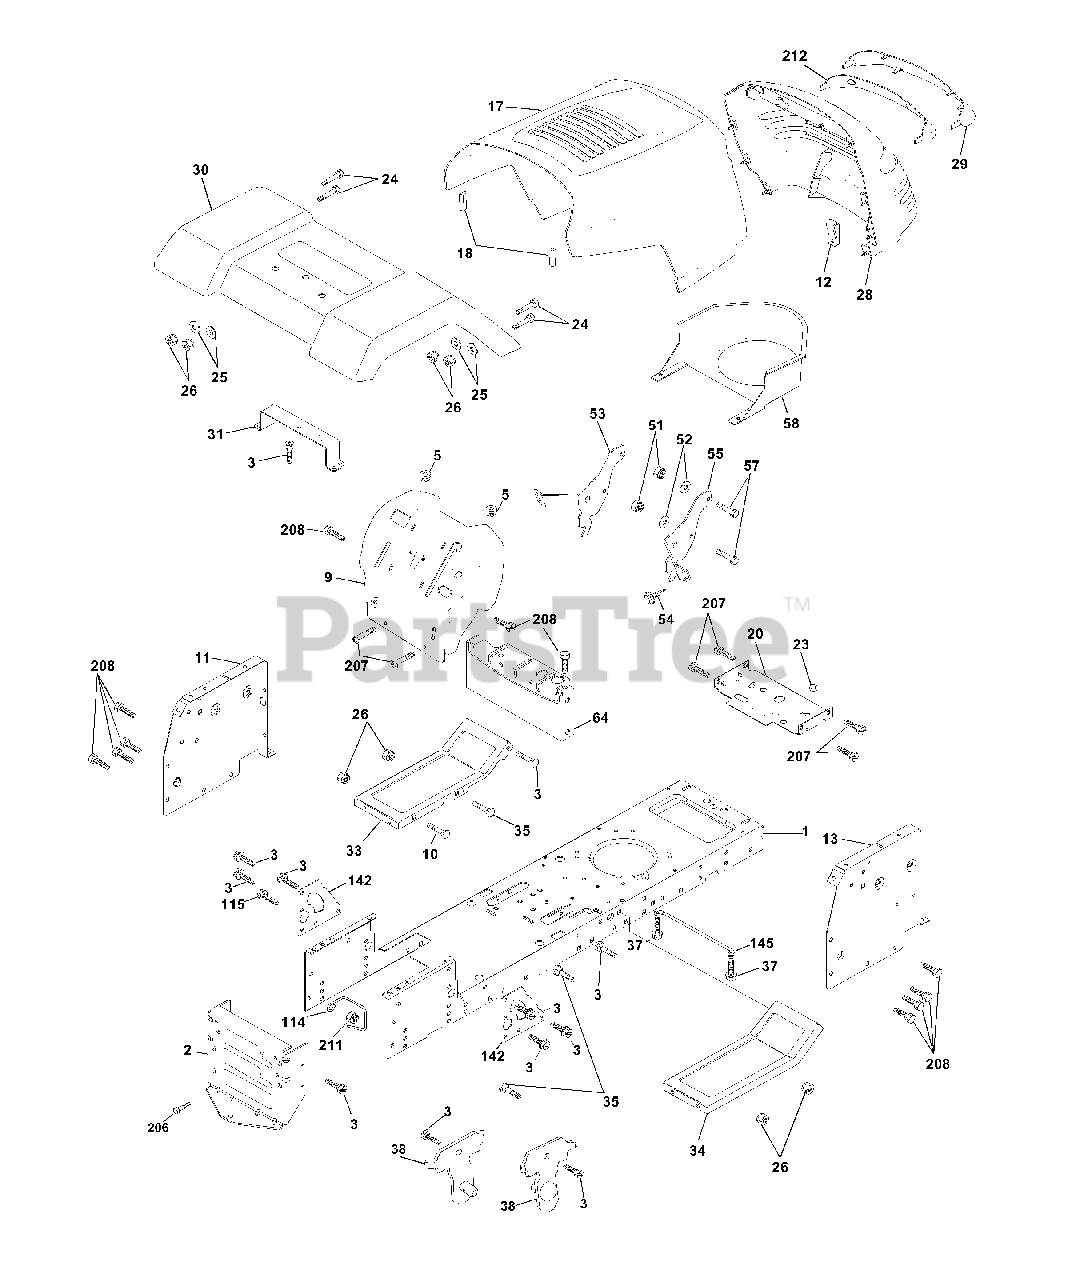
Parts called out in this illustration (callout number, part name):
1	Chassis
2	Drawbar
3	Screw 3/8-16x.75
5	Bumper Hood/Dash
9	Dash P/L
10	Bolt Carriage 3/8-16 x 1
11	Panel Dash Lh
12	Clip Tinnerman
13	Panel Dash Rh
17	Hood LT/PL
18	Bumper Hood
20	Plate Mtg Battery Fuel Tank Fr
23	Bushing
24	Bolt Fin Hex 3/8-16 x 1 Gr 5
25	Washer 13/32 X 13/16 X 12 Ga
26	Nut Lock Hex W/Ins 3/8-16 Unc
28	Grille LT/PL
29	Lens LT/PL
30	Fender Footrest STLT Pnt
31	Bracket Support Fender
33	Footrest Pnt Lh
34	Footrest Pnt Rh
35	Bolt Rdhd Sht Sqnk 3/8-16 x 3/4
37	Screw Thdrol 6/16-18 x 1/2 TYT
38	Bracket Asm. Pivot Mower Rear
51	Nut Lock Hex W/Ins 1/4-20
52	Washer 9/32 x 7/8 x 16 Ga.
53	Bracjet Grukke Lh
54	Screw Hex Wshd 8-18 x 7/8
55	Bracket Grille Rh
57	Bolt Hex 1/4-20 x 3/4
58	Duct Air
64	Dash Lower STLT
114	Keeper Belt Rear Lh
115	Screw 3/8-16 x 1-1/4
142	Plate Reinforcement STLT
145	Rod Pivot Chassis/Hood
206	Bolt Shoulder 5/16-18
207	Screw Thdrol 5/16-18 x 1/2
208	Screw Thdrol 3/8-16 x 1/2
211	Nut Hex flange Lock
212	Insert Lens Reflect P/L LT
